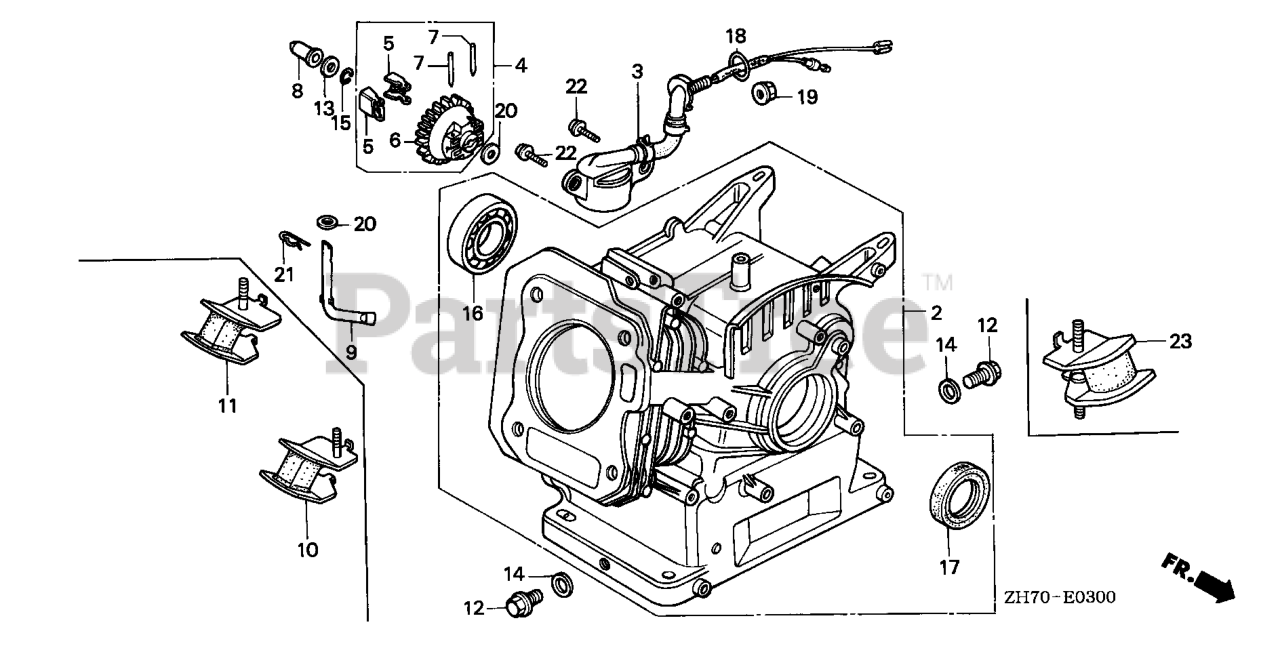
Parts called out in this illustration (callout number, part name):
2	CYLINDER ASSY.
3	SWITCH ASSY., OIL LEVEL
4	GOVERNOR ASSY.
5	WEIGHT, GOVERNOR
6	HOLDER, GOVERNOR WEIGHT
7	PIN, GOVERNOR WEIGHT
8	SLIDER, GOVERNOR
9	SHAFT, GOVERNOR ARM
12	BOLT, DRAIN PLUG
13	WASHER, THRUST (6MM)
14	WASHER, DRAIN PLUG (10.2MM)
15	CLIP, GOVERNOR HOLDER
16	BEARING, RADIAL BALL (62/22)
17	OIL SEAL (22X35X6)
18	O-RING (14MM) (ARAI) Use up to Engine SN 2949254.
19	NUT, FLANGE (10MM)
20	WASHER, PLAIN (6MM)
21	PIN, LOCK (8MM)
22	BOLT, FLANGE (6X12) Use up to Engine SN 1543277.
